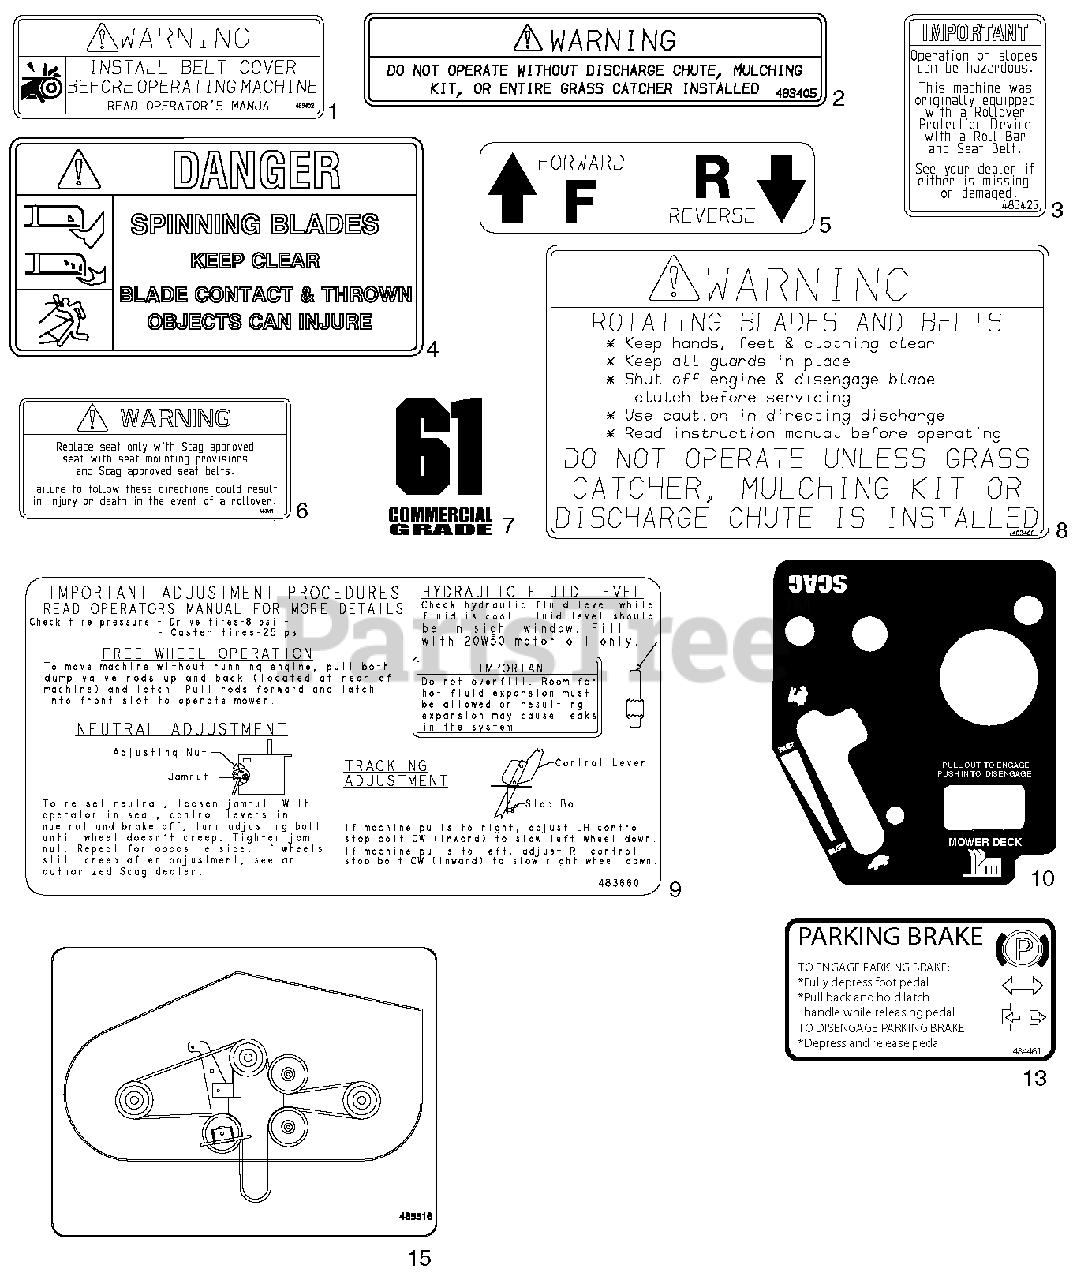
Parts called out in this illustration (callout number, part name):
1	Decal, Belt Cover
2	Decal, Warning
3	Decal, ROPS
4	Decal, Spinning Blades
5	Decal, Traction Control
6	Decal, Seat Replacement
7	Decal, 52 Commercial
7	Decal, 61 Commercial
8	Decal, Knives
9	Decal, Adjustment SPZ
10	Decal, Instrument Panel
13	Decal, Brake
15	Decal, SZL / SFZ / SPZ Belt Routing
